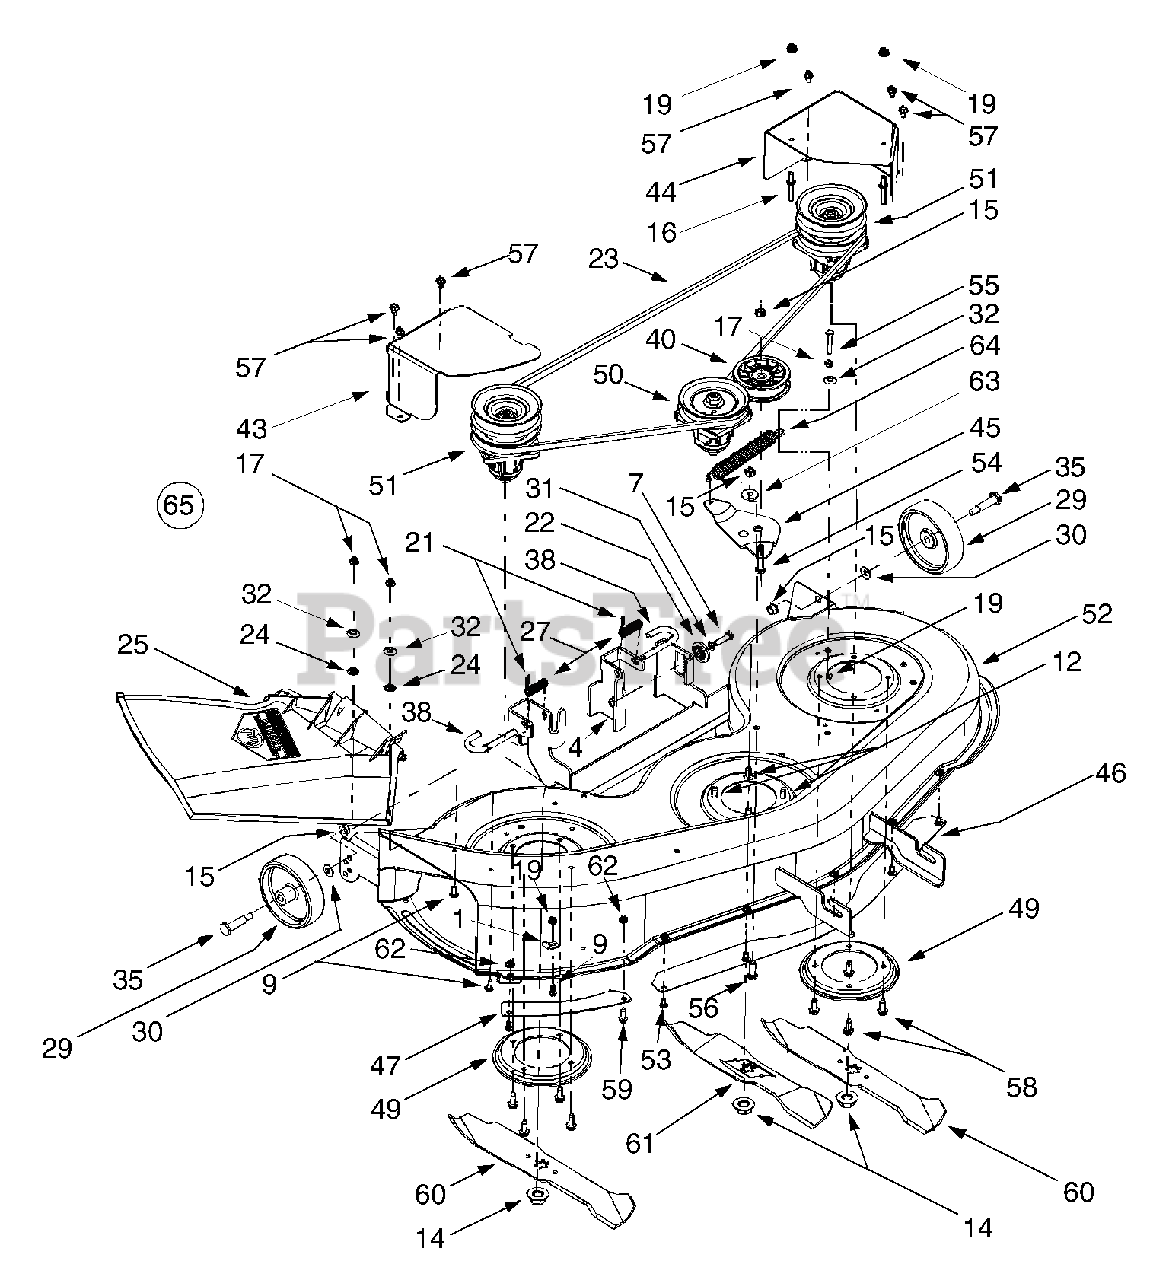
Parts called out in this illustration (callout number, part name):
1	Retainer Hook
7	Hex Cap Screw, 5/16-18 x 1.25
9	Hex Cap Screw, 1/4-20 x .62
12	Self-tapping Screw, 5/16-18 x .75
14	Hex Flange Nut, 5/8-18
15	Flange Lock Nut, 3/8-16
16	Belt Keeper Pin
17	Hex Nut, 1/4-20
19	Hex Flange Lock Nut, 1/4-20
21	Cotter Pin, 3/32 x 1.0
22	Deck Adjustment Gear
23	Deck Belt
24	Push Nut. .25 x .5
25	Side Discharge Chute Assembly
27	Compression Spring, .406 x .531 x 1.75
29	Deck Wheel, 5 x 1.38
30	Bell Washer, .401 x .87 x .063
31	Lock Washer, 5/16
32	Bell Washer, .265 x .75 x .062
35	Shoulder Screw, .498 x 1.53
38	Deck Release Pin
40	Flat Idler Pulley, 3.5 OD
49	Reinforcement Spindle Plate
50	Spindle Assembly, 5.0 Dia.
51	Double Pulley Spindle Assembly
54	Hex Cap Screw, 3/8-16 x 1.75
55	Hex Cap Screw, 1/4-20 x 2.0
56	Hex Cap Screw, 3/8-16 x 1.0
57	Self-tapping Screw,1/4-20 x .5
58	Self-tapping Screw,15/16-18 x .875
59	Hex Screw, 1/4-20 x .75
60	Three-in-one Blade, Star Center, 16.28"
61	Three-in-one Blade, Star Center, 14.88"
62	Hex Sems Nut, 1/4-20
63	Shoulder Spacer, .625 x 1.16
64	Extension Spring, .91 x 7.33
